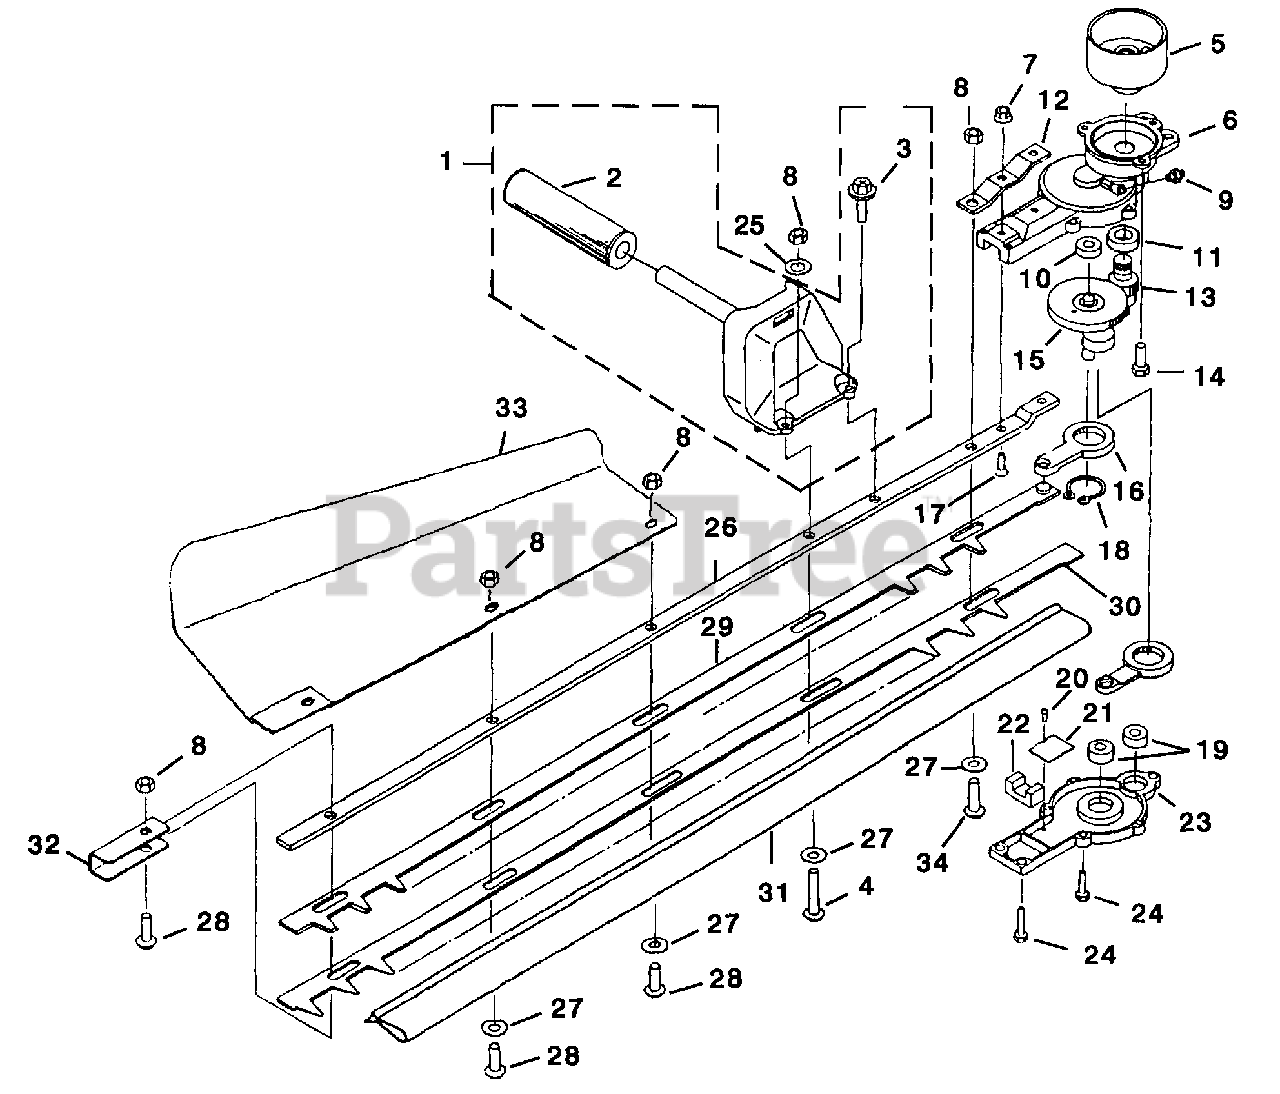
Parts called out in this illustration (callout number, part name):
1	FRONT HANDLE ASSEMBLY
3	SCREW (M5 x 20 SW & PW)
4	SCREW (L-29)
5	DRUM-Clutch
6	CASE-Upper
7	NUT-Flange (M5)
8	NUT (M6)
9	NIPPLE-Grease (M6)
12	PLATE-Reinforcing
13	GEAR-Pinion
14	BOLT (M6 x 15 W SW)
15	GEAR CRANK ASSEMBLY
17	SCREW (M5 x 20)
18	SNAP RING
20	SCREW (M3 x 5)
21	PLATE-Rod Slide
23	LOWER CASE
24	BOLT (M5 x 16 W SW)
26	GUIDE PLATE
27	WASHER-Blade Side
28	SCREW (L-19)
29	BLADE-Upper
30	BLADE-Lower
31	BLADE COVER
32	BLADE-End Reinforcer
33	RECEIVER PLATE
34	SCREW (L-22)
